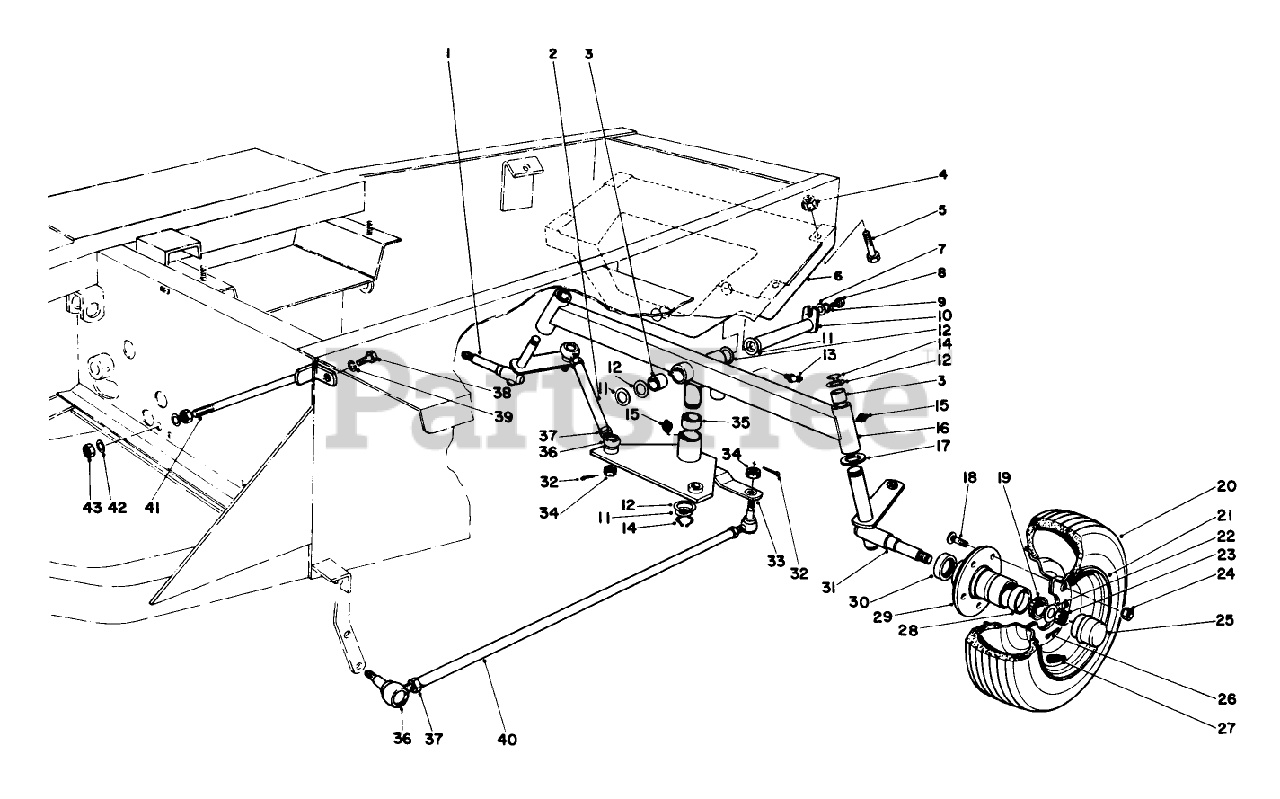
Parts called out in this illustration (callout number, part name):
1	Spindle Assembly R.H.
2	TIE ROD-STEERING
3	BUSHING
4	NUT-HF
5	SCREW-HH
6	REAR AXLE MT R
7	WASHER-PLAIN
8	SCREW-HH
9	WASHER-LOCK
10	REAR AXLE PIN WA
11	WASHER
12	WASHER-THRUST
13	FITTING-LUBE, 45 DEG
14	RING-RETAINING
15	FITTING-GREASE
16	Rear Axle (Incl. Ref. #3)
17	WASHER-THRUST
18	STUD-TYPE, DRIVE
19	BEARING-CONE, TAPERED
20	TIRE-Ribbed
21	WHEEL-8 INCH
22	WASHER-FLAT
23	NUT-HEX, SLOTTED
24	NUT-LUG
25	CAP-DUST
26	PIN-COTTER
27	STEM-VALVE
28	BEARING-CUP, TAPERED
29	Wheel Hub (Incl. Ref. #18 & 28)
31	Spindle Assembly L.H.
32	PIN-COTTER
33	Rear Steering Pivot (Incl. Ref. #35)
34	NUT-SLOTTED
35	BUSHING
36	Socket R.H. Thread (Incl. Ref. #34)
37	NUT-JAM
38	SCREW-HH
39	WASHER-LOCK
40	REAR STRG TUBE PP
41	Axle Support
42	WASHER-FLAT
43	NUT-HH
